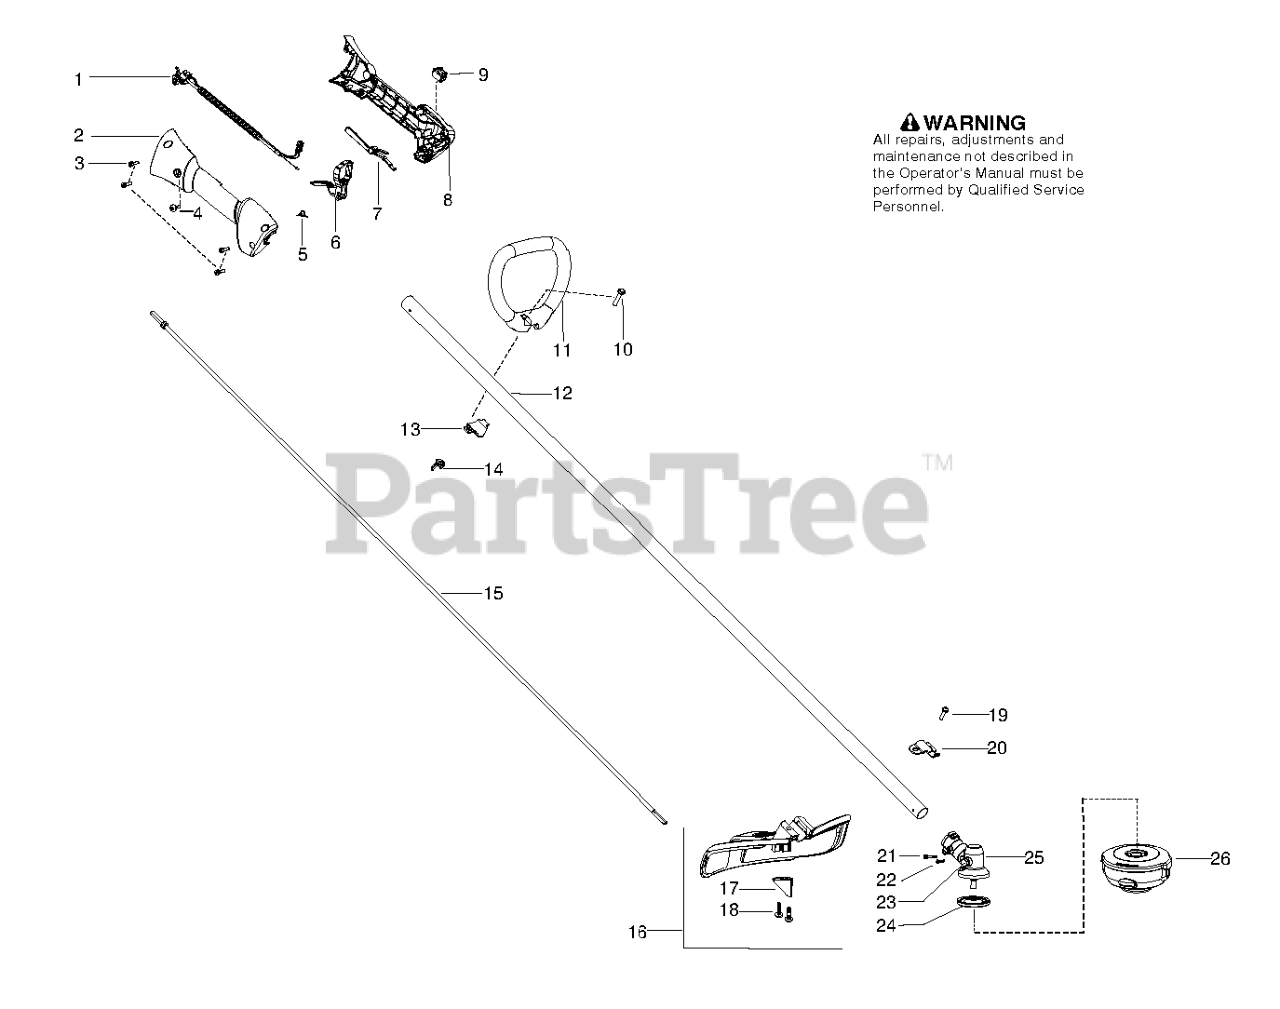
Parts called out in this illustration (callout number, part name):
1	ASSY CABLE / WIRE HARNESS
2	HSG THROTTLE RIGHT HVA
3	SCREW M4 X 1.75 PT 16MM
4	SCREW-10-14 X 1/2 PLASTITE
5	SPRING TRIGGER
6	TRIGGER THROTTLE HVA ORANGE
7	THROTTLE LOCKOUT HVA ORANGE
8	HSG THROTTLE LEFT HVA
9	SWITCH
10	BOLT, TYPE 2
13	CLAMP ASSIST HANDLE
14	WINGNUT, TYPE 2
15	FLEXSHAFT 57"
16	KIT COBI SHIELD
17	Limiter - Line
19	SCREW 1/4-20 X 7/8 (TAP
20	BRACKET SHIELD STRAIGHT SHAFT
21	SCREW - CARB. ADAPTOR
23	PLUG GREASE 9MM
24	DRIVE DISC
25	ASSY GEARBOX
26	T25 TRIM HEAD 10MM LH
